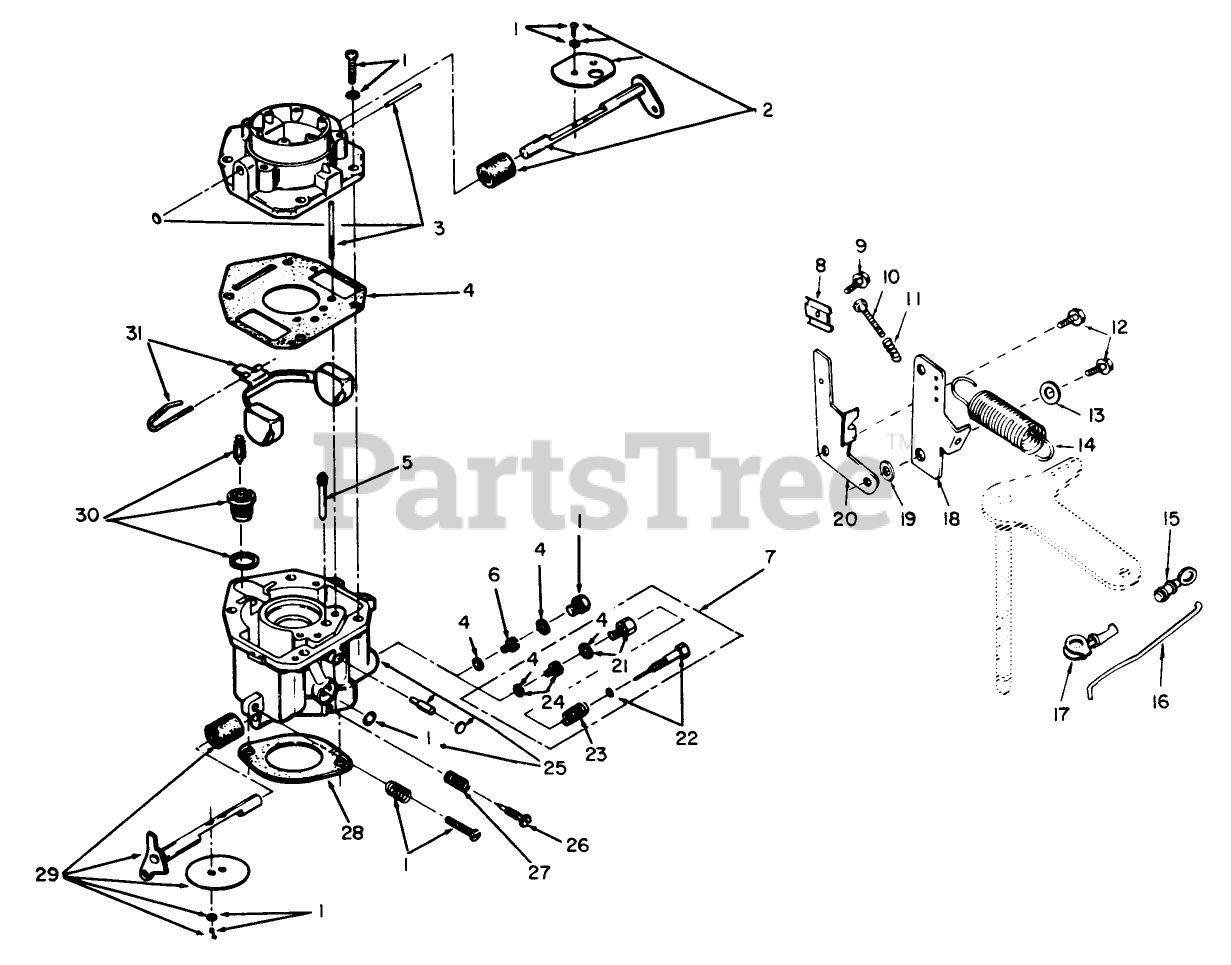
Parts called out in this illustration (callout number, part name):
1	Screw and Plug Kit
2	Choke, Shaft Kit
3	Intake, Air
4	Gasket Kit
5	Jet, Idle
6	Jet, Power
7	Variable Speed Jet Kit-Optional (High Altitude Application)
8	Clamp, Cable
9	Screw, Tapping Hex. Hd.
10	Screw, Tapping Hex Head
11	Spring Idle Setting
12	Screw-Cap Hex Washer Hd.
13	Washer, Flat
14	Spring, Governor
15	Clip, Retaining-Control Rod
16	Rod, Governor Control
17	Clip, Retaining-Control Rod
18	Arm-Governor Control
19	Bushing Control Arm
20	Bracket Cable
21	Retainer, Power Needle (Incl. Gasket)
22	Needle Complete Power
23	Spring, Power Needle
24	PowerJet, Variable (Incl. Gasket)
26	Needle, Idle Adjusting
27	Spring, Idle Adjusting Needle
28	Gasket Carburetor Mounting
29	Throttle Shaft Kit
30	Valve Seat Kit
31	Float Kit
